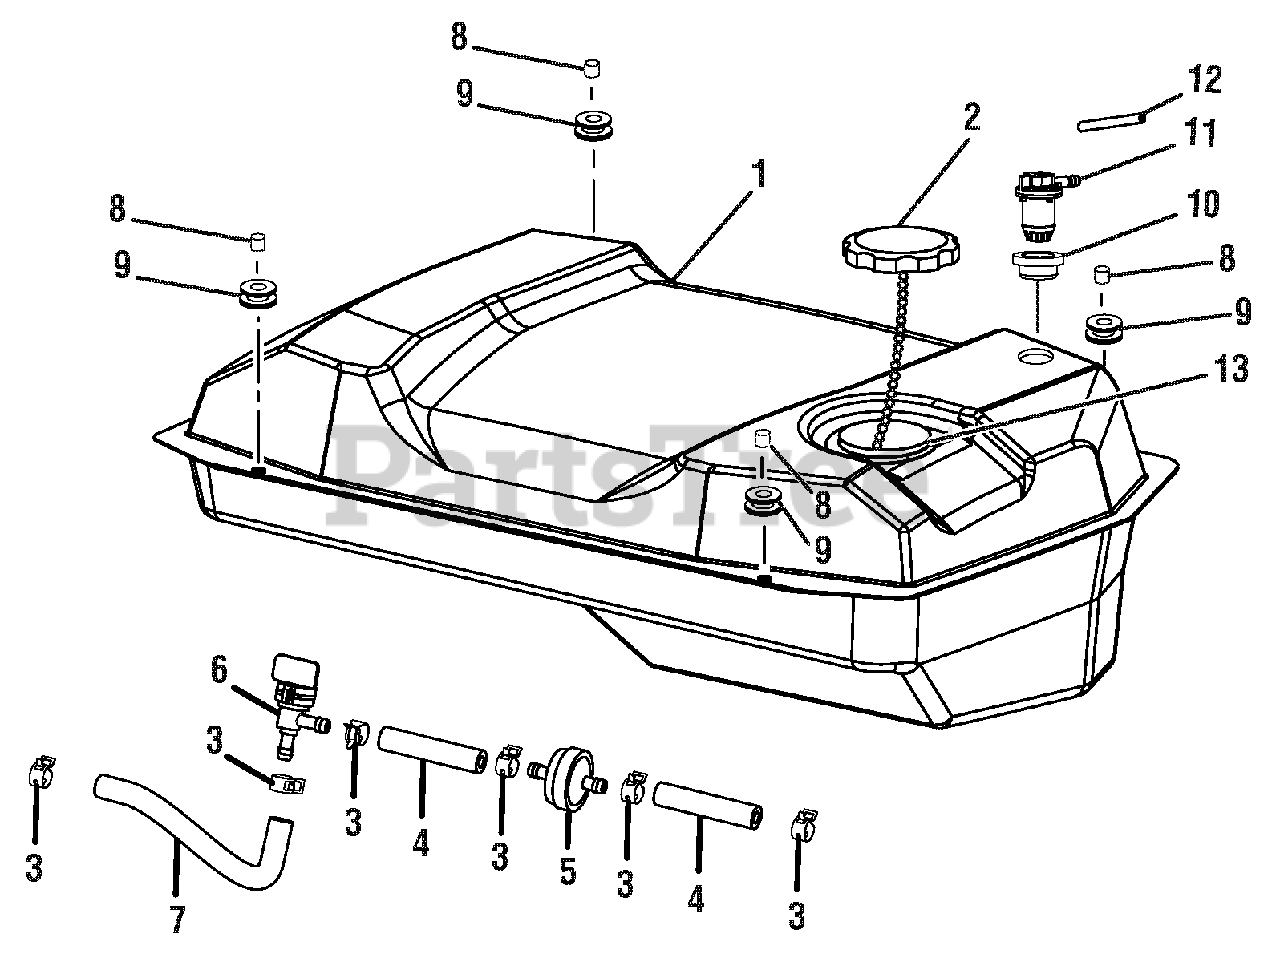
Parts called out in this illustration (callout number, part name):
1	Fuel Tank
2	Fuel Tank Cap
3	Fuel Line Clamp (1/2 in.)
4	Fuel Line (105 mm)
5	Fuel Filter
6	Fuel Shut Off Valve
7	Fuel Line (208 mm)
8	Spacer (Fuel Tank Isolator)
9	Bushing (Fuel Tank Isolator)
11	Rollover Valve
12	Purge Hose
13	Ring Clip
